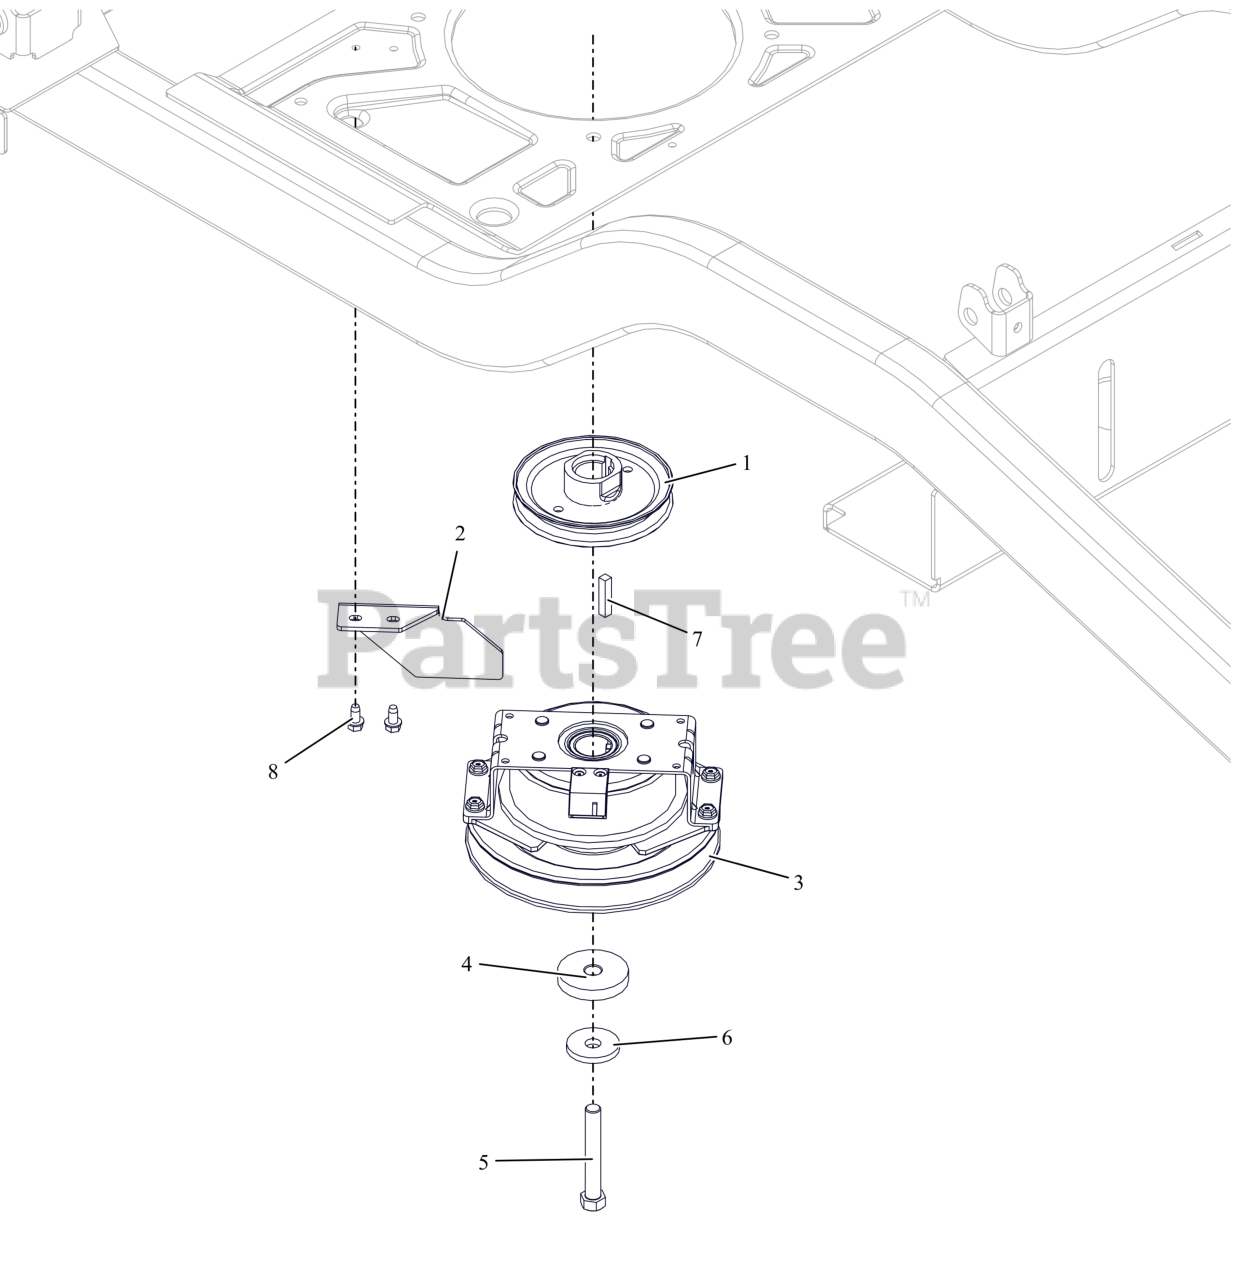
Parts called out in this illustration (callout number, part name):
1	WLDMT,PULLEY-4.50ODX1.003
2	BRKT, CLUTCH STOP HD
3	CLUTCH, OGURA DBL SPRG
4	SPACER, .474/.459X2.00X.350
5	BLT, HEX .44-20X3.00 G8 ZCC NT
6	WASHER, 7/16" SPRING DISK
7	KEY-SQ .25 X 1.25 X .25 SAE
8	SCR-TAP .25-20X.50 HWH ZCC
